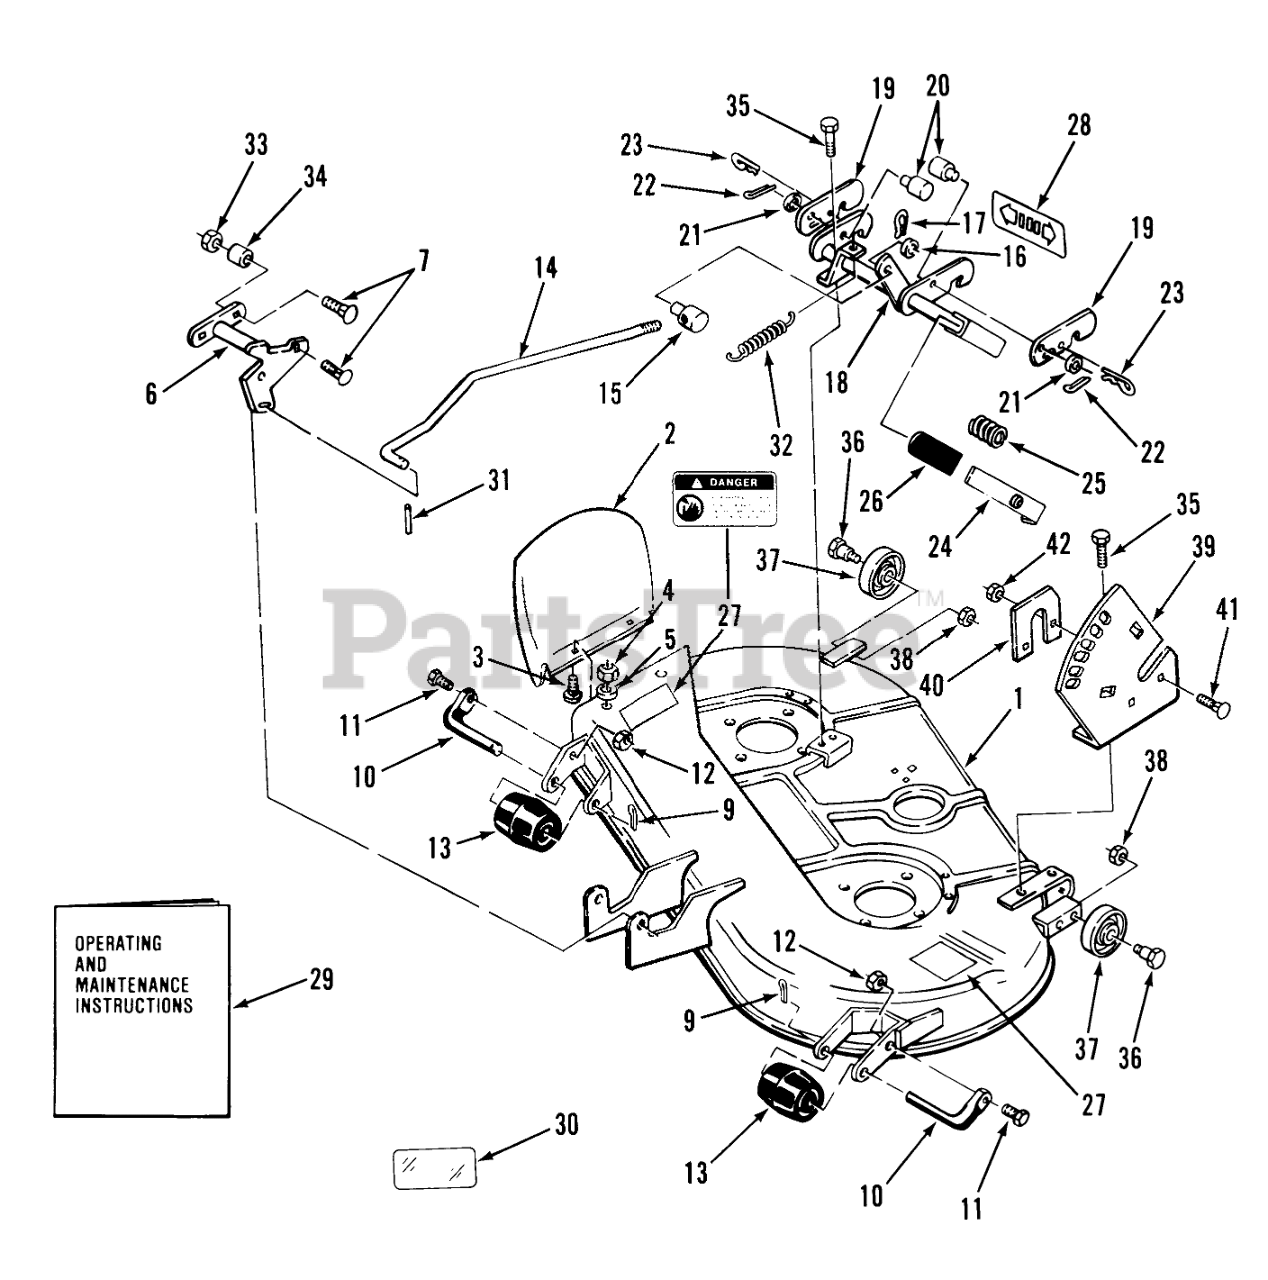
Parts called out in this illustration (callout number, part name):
1	Deck-Mower
2	Chute Extension
3	Bolt
4	Nut
5	Washer 5/16
6	ASM-FRONT LIFT R
7	Bolt-Carriage
9	Cotter Pin
10	ROLLER-SHAFT
11	Bolt
12	Nut
13	Roller
14	ASS'Y-HEIGHT ADJ R
15	STUD-TRUNION
16	Washer
17	Hairpin Cotter
18	HT. ADJ. SHAFT
19	Latch
21	Washer
22	Cotter Pin
23	Hairpin Cotter
24	LEVER ASSY
25	SPRING-COMPRESSION
27	Danger Decal
28	DECAL-HOC
29	Operating and Maintenance Instructions
30	DECAL-OVERLAY
31	SPIROL PIN
32	SPRING-EXTENSION
33	LOCKNUT-FLANGE
34	SPACER
35	Bolt
36	BOLT-SHOULDER
37	WHEEL-GAGE
38	NUT
39	Quadrant
40	PLATE-RETAINING R
41	Bolt
42	Nut
